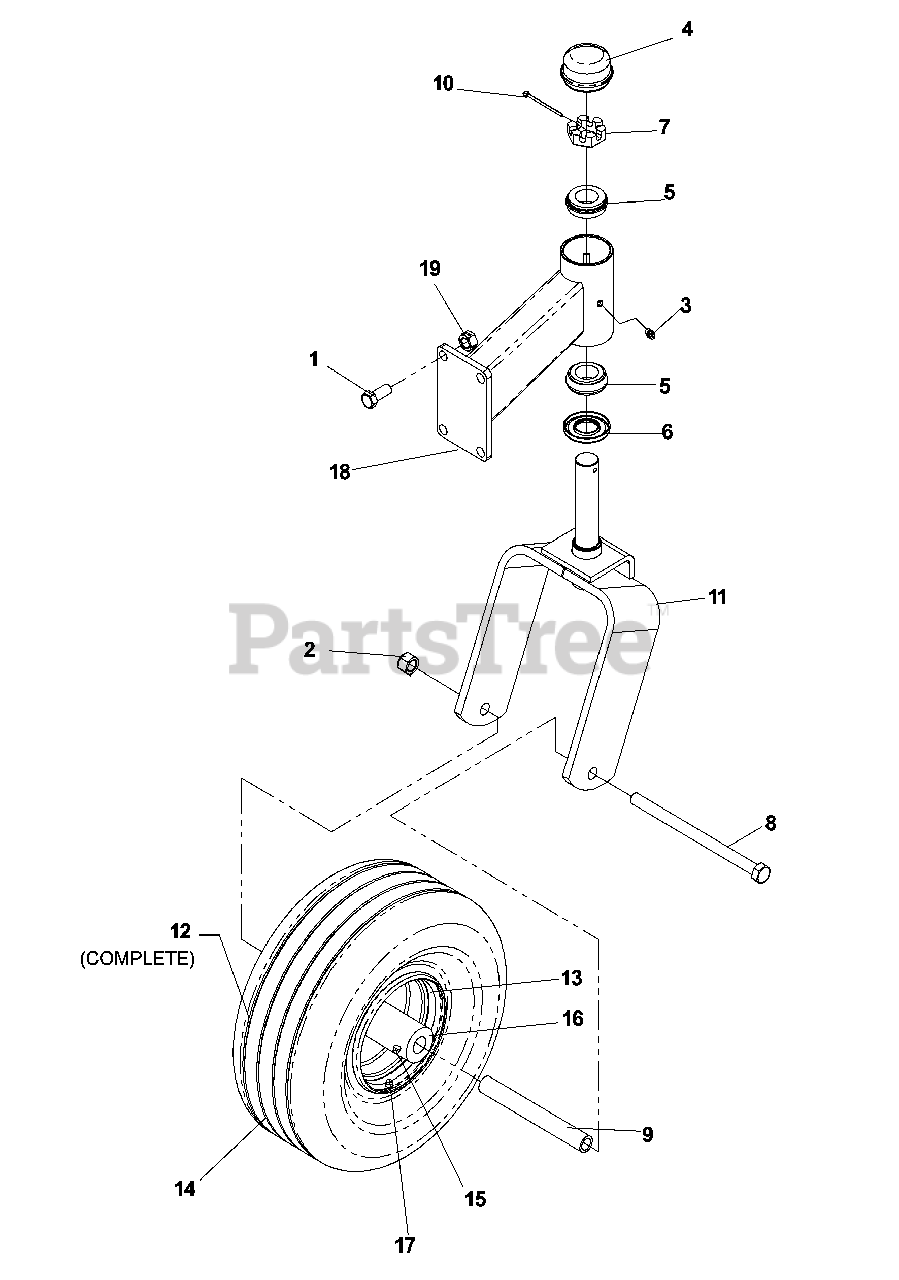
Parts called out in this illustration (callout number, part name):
1	HCS 7/16-14 X 1 GR 5 ZD
2	NUT 1/2-13 HEX NYLOC ZD
4	GREASE CAP
5	TAPERED ROLLER BRG
7	NUT 1"C HEX SLOTTED
8	SCREW 1/2C X 7 1/2 HEX CAP
9	SPACER, CASTER
10	COTTER PIN 1/8 X 2
11	YOKE, CASTER, BLUE
12	TIRE.ASSEM.13X5-6.SMOOTH.SILVE
13	Tire Assembly, Complete
14	TIRE - FRONT
15	ZERK 1/8 NPT
16	BEARING RETAINER
17	VALVE STEM TR-412
18	ARM, CASTER, BLUE
19	NUT 7/16C CENTERLOCK
